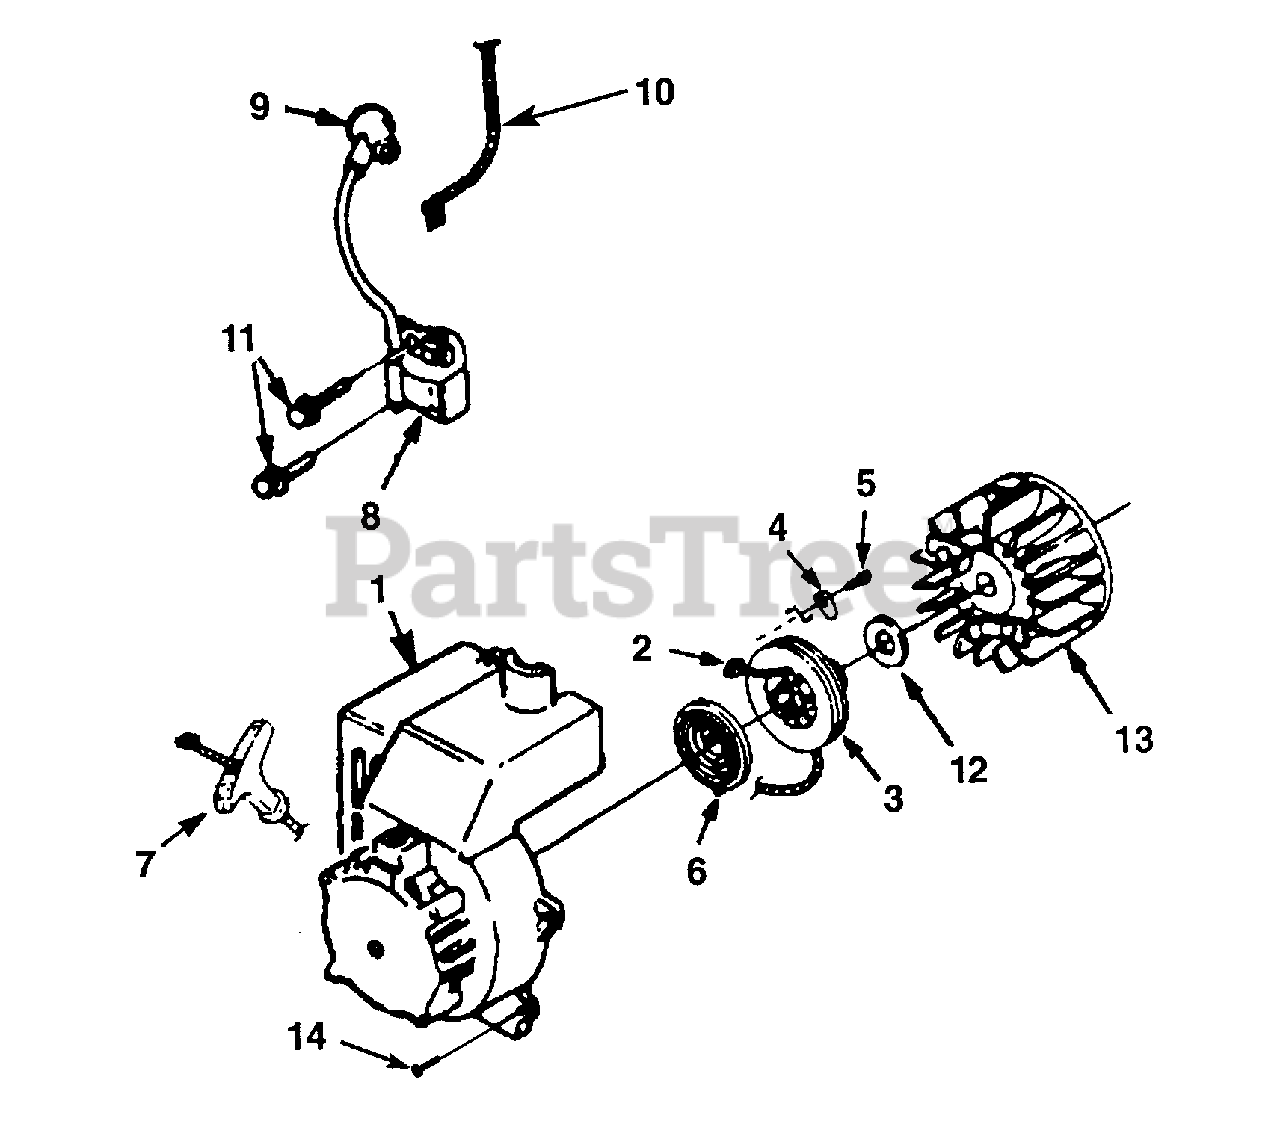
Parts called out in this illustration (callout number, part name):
1	Starter/Engine Housing
2	Starter Rope (42")
3	Starter Pulley
4	Retaining Bracket
5	Screw - Plastite (10 X 1/2")
6	Spring & Container
7	Starter Grip
8	Ignition Module
9	Terminal & Cover
10	Electrical Lead
11	Screw - Thread Forming (8-32 X 1")
12	Flat Washer
13	Rotor & Starter Pawls
14	Screw - Thread Forming (10-24 X 3/4")
